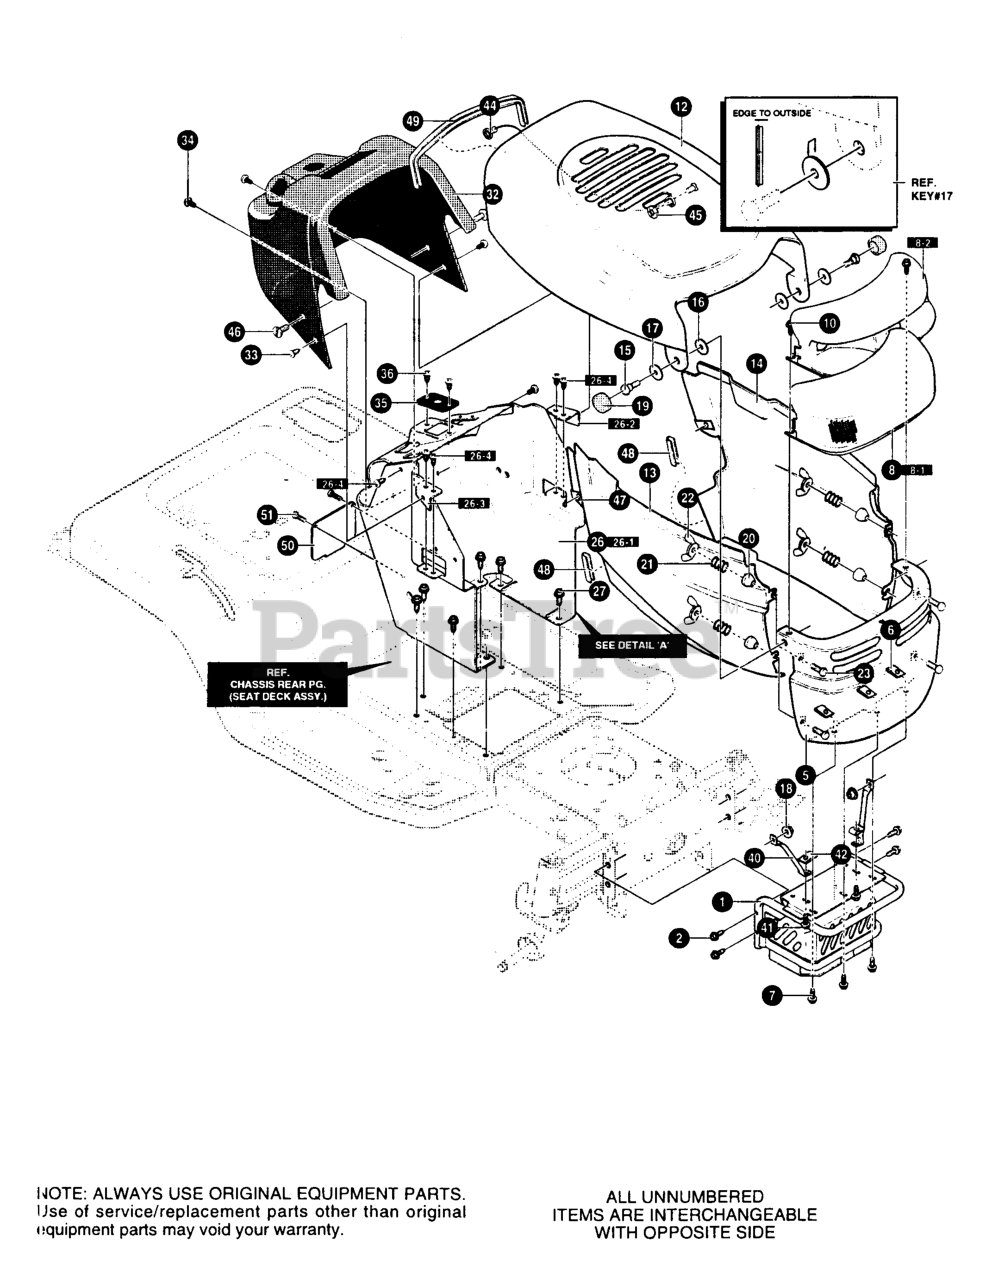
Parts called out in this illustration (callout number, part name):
1	WELD. ASM. COMMON BUMP/GRIL MNT
2	SCREW 5/16-18X1.50 HHWATAP
6	NUT, "J" TINNERMAN #C702-14202
7	SCREW 1/4-20X.63 HHWATAPSERBZ
8	ASM. LENS & REFLECTOR
8-2	REFLECTOR
10	SCREW, 1/4-14X.50 PANCR
12	WELD ASSEMBLY HOOD
13	PANEL, SIDE RH
14	PANEL, SIDE LH
15	BOLT, .497X.215HHSH 3/8-16
16	WASHER, PLASTIC
17	PIVOT BASE
18	NUT, 3/8-16 HWDFLLK MACK 15X84
19	CAP, PIVOT
20	QUICK RELEASE-CAM
21	SPRING, COMP.500DX.5LG
22	NUT, WING 1/4-20 NYLON
23	SCREW, 1/4-20X1.25
26	CONSOLE ASSY
26-1	CONSOLE DASH MAN PTO
26-2	BRACKET, HOME DEPOT LH
26-3	BRACKET, HOME DEPOT RH
26-4	SCREW, 10-24X.500 SEGI
27	SCREW 5/16-18HHWATAP
33	SCREW 10-24X.500TRSEGI
34	SCREW 10-24X.500TRSEGI
35	BRACKET, STEERING
36	SCREW, 1/4-14X.50 PANCR
40	STRUT, GRILLE
41	SCREW 1/4-20X.63 HHWATAP
42	SPEED NUT
44	LANYARD, HOOD
45	PUSHNUT
46	SCREW, 1/4-20X.63 PHPNHD
47	NUT, "J" TINNERMAN #C702-14202
48	TRIM, PIECE PLASTIC
49	TRIM, PIECE PLASTIC
50	ACCESS PANEL W/O SLOT
51	SCREW 10-24X.500TRSEGI
